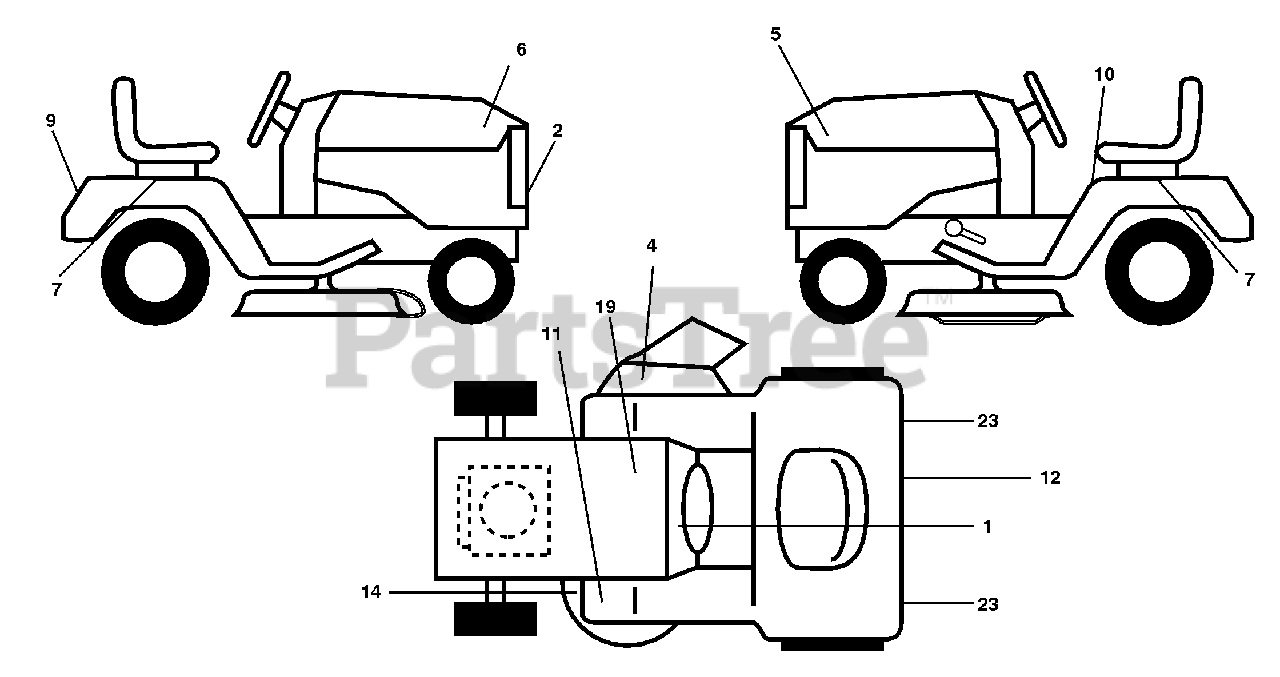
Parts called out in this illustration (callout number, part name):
1	Decal, Operating Instruction
2	Decal, Grille Husqvarna
4	Decal, Warning, Mult. Lang.
5	Decal, Hood LH GTH200
6	Decal, Hood RH GTH200
7	Decal, Fender Automatic Husq.
9	Decal, Fender
10	Decal, Danger
11	Decal, Clutch/Brake
12	Decal, Brake Parking Saddle
14	Decal, V-Belt Schematic
19	Decal, Battery
23	Reflector, Taillight
